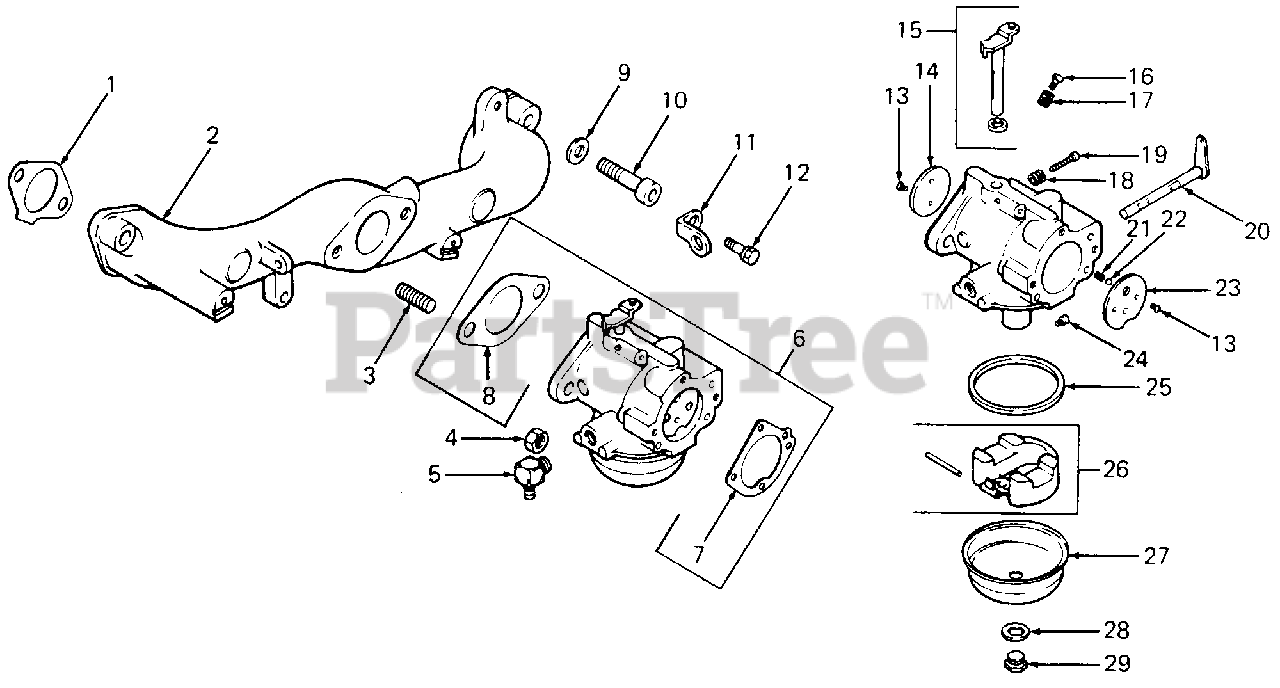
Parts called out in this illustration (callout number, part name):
1	Gasket, Manifold
2	Manifold, Intake
3	Stud, 5/16-18 X 1
4	Nut, Hex, 5/16-18
5	Connector, 90 Hose
6	Carburetor Assy w/ Gasket
7	Gasket, Air Intake Elbow
8	Gasket, Carburetor
9	Washer, Plain, 5/16
10	Screw, Hex Socket, 5/16-18 X 1-1/4
11	Strap, Hanging
12	Screw, Hex Wash, 1/4-20 X 5/8
13	Screw, Throttle & Choke Plate
14	Plate, Throttle
15	Shaft, Throttle w/ Lever & Seal
16	Needle, Idle Fuel Adj
17	Spring, Idle Fuel
18	Spring, Idle Speed
19	Screw, Idle Speed Adj
20	Lever, Choke
21	Spring, Choke Friction
22	Ball, Choke Friction
23	Plate, Choke
25	Gasket, Bowl
28	Gasket, Bowl Retainer Screw
29	Screw, Bowl Retainer
